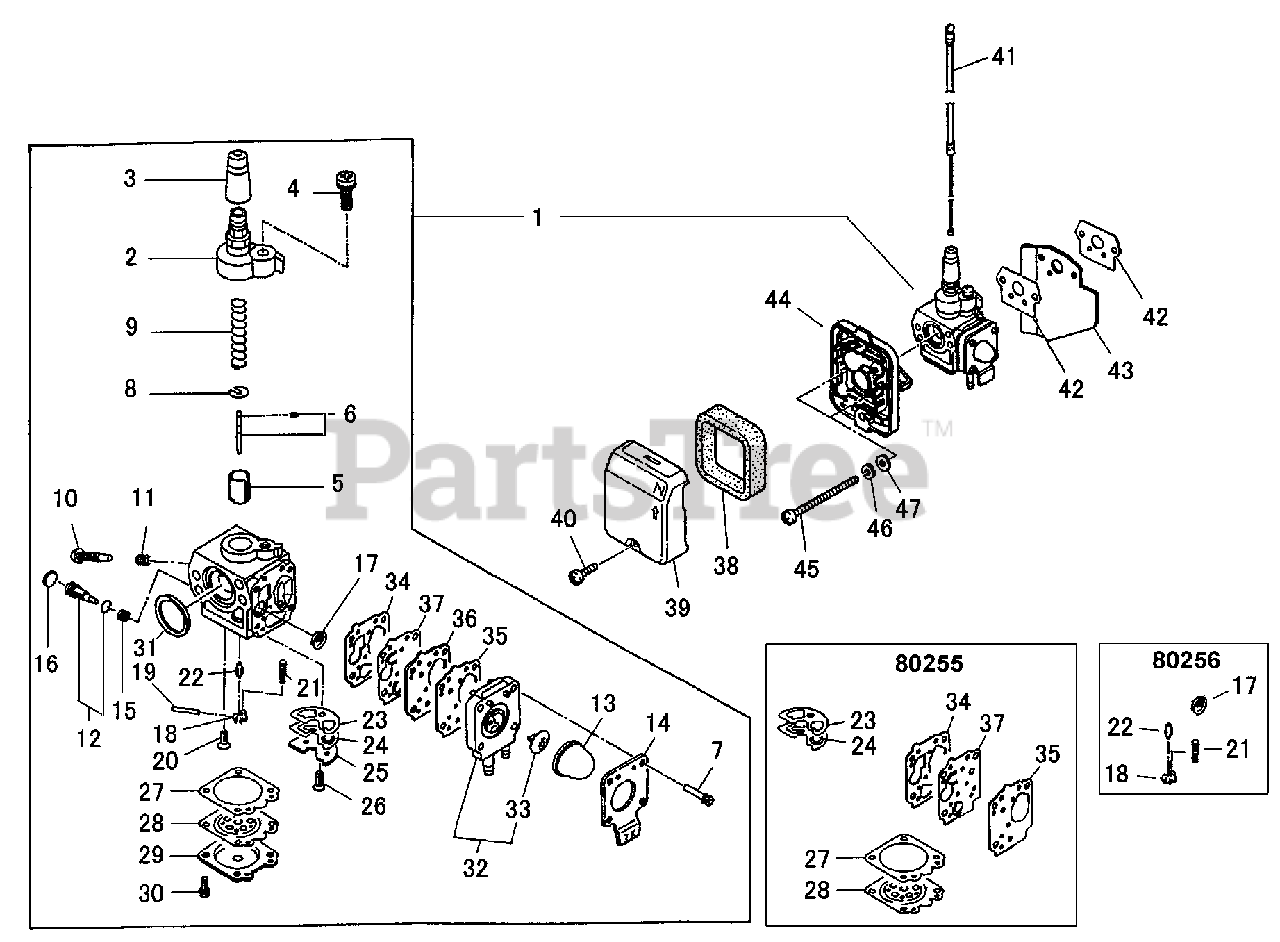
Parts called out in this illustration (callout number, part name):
1	CARBURETOR
2	CAP, CARBURETOR
3	CAP, DUST
4	SCREW
5	VALVE, SLIDE
6	NEEDLE, JET
7	SCREW - 3X14
8	SEAT, SPRING
9	SPRING
10	SCREW, IDLE ADJUST
11	SPRING
12	SCREW, MAIN ADJUST
13	BULB, PURGE
14	COVER, PUMP
15	SPRING
16	PLATE
17	STRAINER
18	LEVER, METERING
19	PIN, METERING LEVER
20	SCREW, METERING LEVER PIN
21	SPRING
22	VALVE, INLET NEEDLE
23	GASKET
24	VALVE, CHECK
25	PLATE
26	SCREW, METERING LEVER PIN
27	GASKET, METERING
28	DIAPHRAGM, METERING
29	COVER, DIAPHRAGM
30	SCREW
31	SEAL
32	BASE, PURGE
33	VALVE
34	GASKET, PUMP
35	GASKET, PUMP
36	PLATE, PUMP
37	DIAPHRAGM, PUMP
38	FILTER, AIR
39	COVER, AIR FILTER
40	SCREW - 5X16
41	CABLE, THROTTLE
42	GASKET, INTAKE
43	GASKET, INTAKE
44	CASE, AIR FILTER
45	SCREW
46	LOCKWASHER - 5
47	WASHER - 5
47	DIAPHRAGM/GASKET KIT
47	REPAIR KIT
